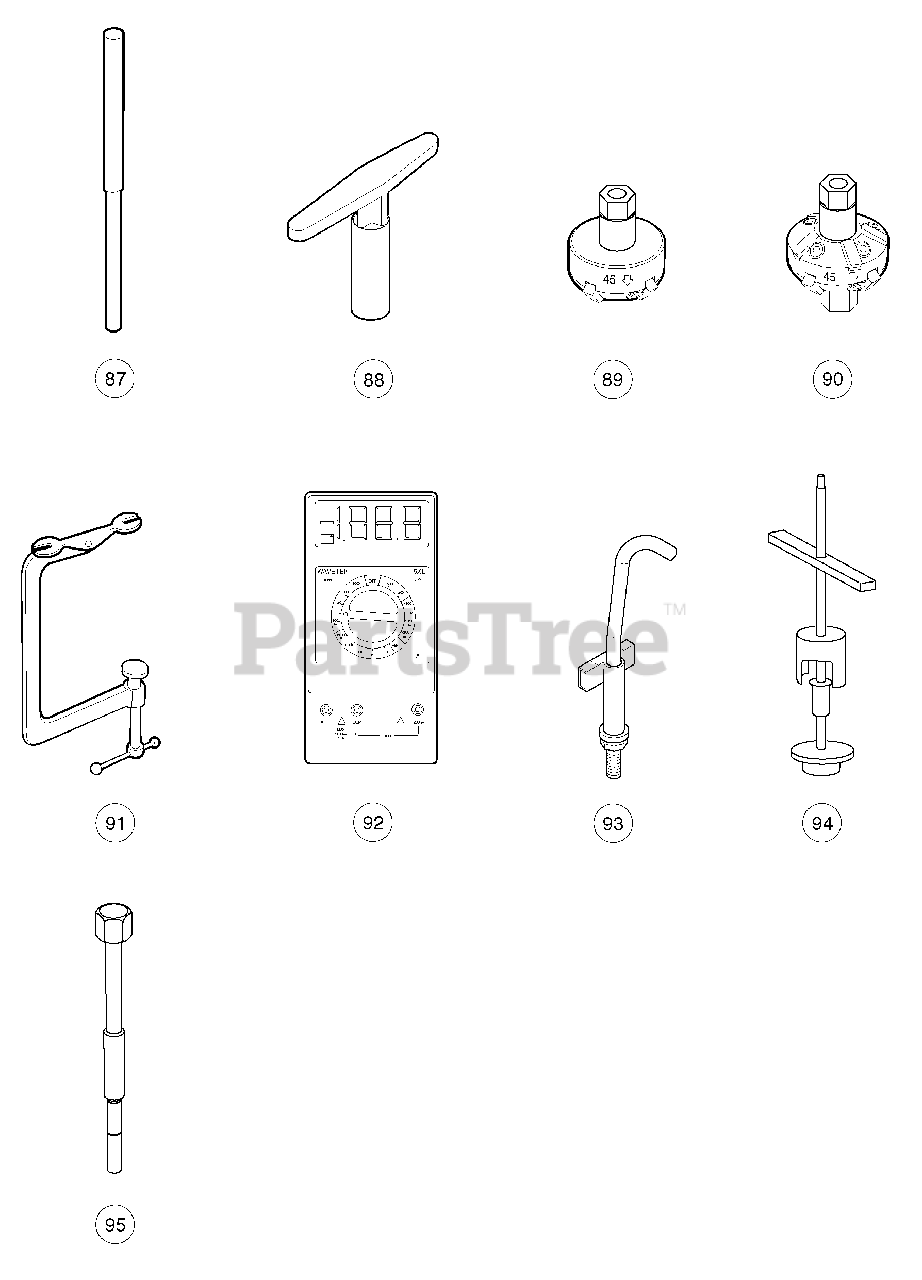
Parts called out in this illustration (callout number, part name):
87	Valve Seat Cutter Guide
88	Valve Seat Cutter T-Wrench
89	Valve Seat Cutter, 45deg (32 mm diameter)
90	Valve Seat Cutter, 45deg/30deg (35 mm diameter)
91	Valve Spring Compressor
92	Volt Ohm Meter
93	Tool, Tensioning, Starter Generator (For Precedent vehicles)
94	Puller, Drive Clutch, XRT 950
95	Tool, Disassembly, Driven Clutch, XRT 950
